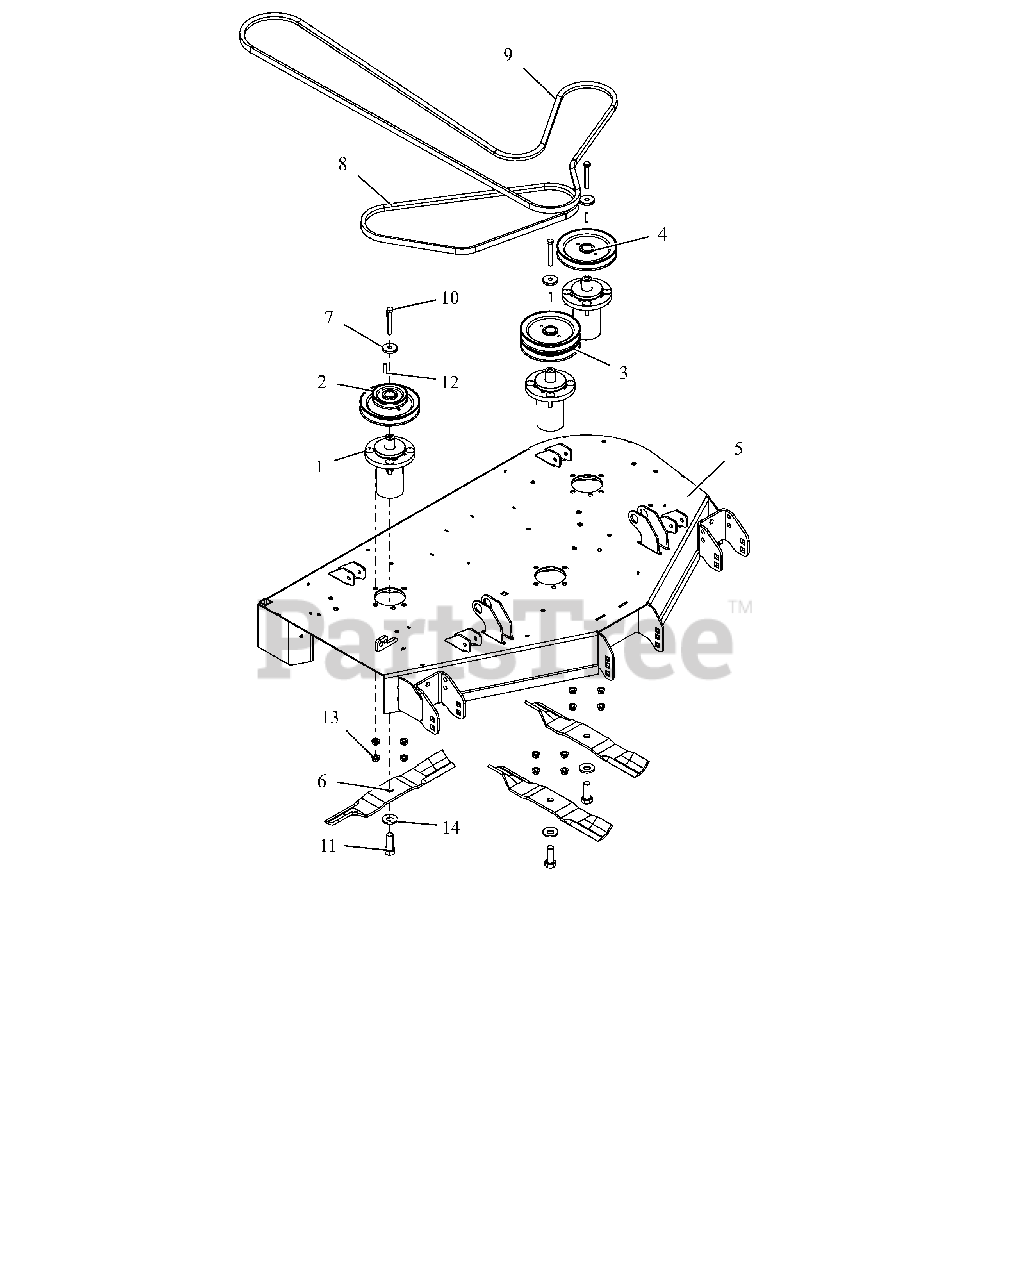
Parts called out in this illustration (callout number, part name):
1	ASM, MAINT FREE ALUM SPINDLE
2	PULLEY, DOUBLE-1"IDX3.50"&6.0
3	PULLEY, DOUBLE
4	PULLEY, SINGLE-1"ID X 6" OD
5	KIT,DECK-44" W/DECALS -GRAVELY
6	BLADE, 16.19" MOWER (HI-LIFT)
7	RETAINER, SHEAVE
8	V-BELT, B-COGGED
9	V-BELT, HB RAW EDGE EPDM
10	BLT-HEX .38-16X2.75 GR8 YWZC
11	BLT-HEX .62-18X1.75 GR8 YWZC
12	KEY, SQ .25X.25X1.00 RC 40-50
13	NUT-LK-CTR-FLG .38-16 YWZC
14	WSHR-BLVL .669X1.535X.138
